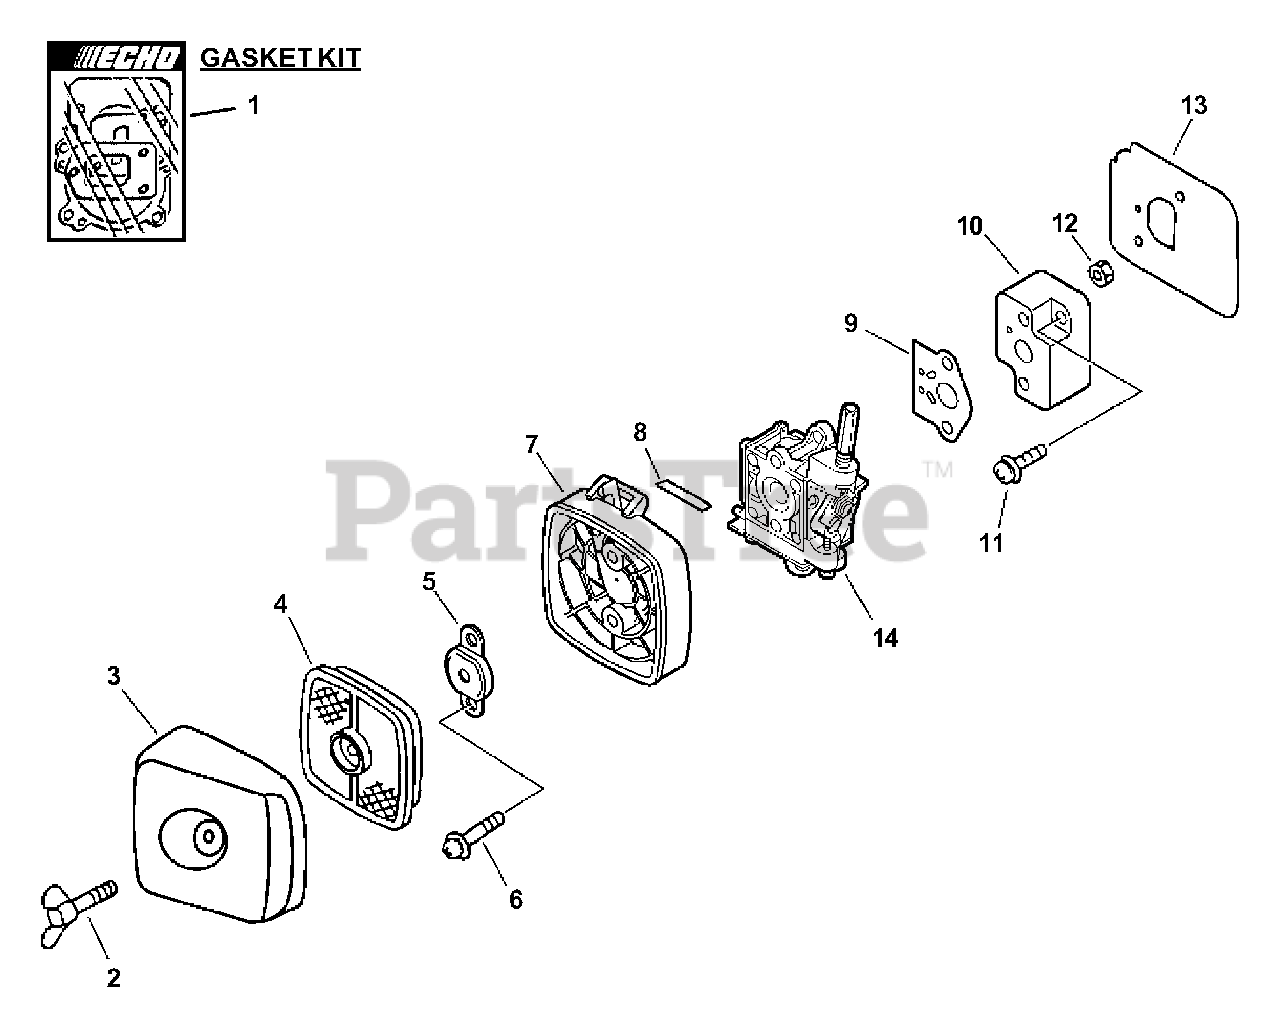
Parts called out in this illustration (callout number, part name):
1	GASKET KIT
2	BOLT, WING 5×20
3	COVER, AIR FILTER - GRAY
4	FILTER, AIR - SINGLE LAYER
5	PLATE, PREVENT
6	SCREW 5×65
7	CASE, AIR FILTER - GRAY
8	LABEL, CHOKE
9	GASKET, CARBURETOR
10	INSULATOR, INTAKE
11	SCREW 5×20
12	NUT M5
13	HEAT SHIELD, INTAKE
14	CARBURETOR
